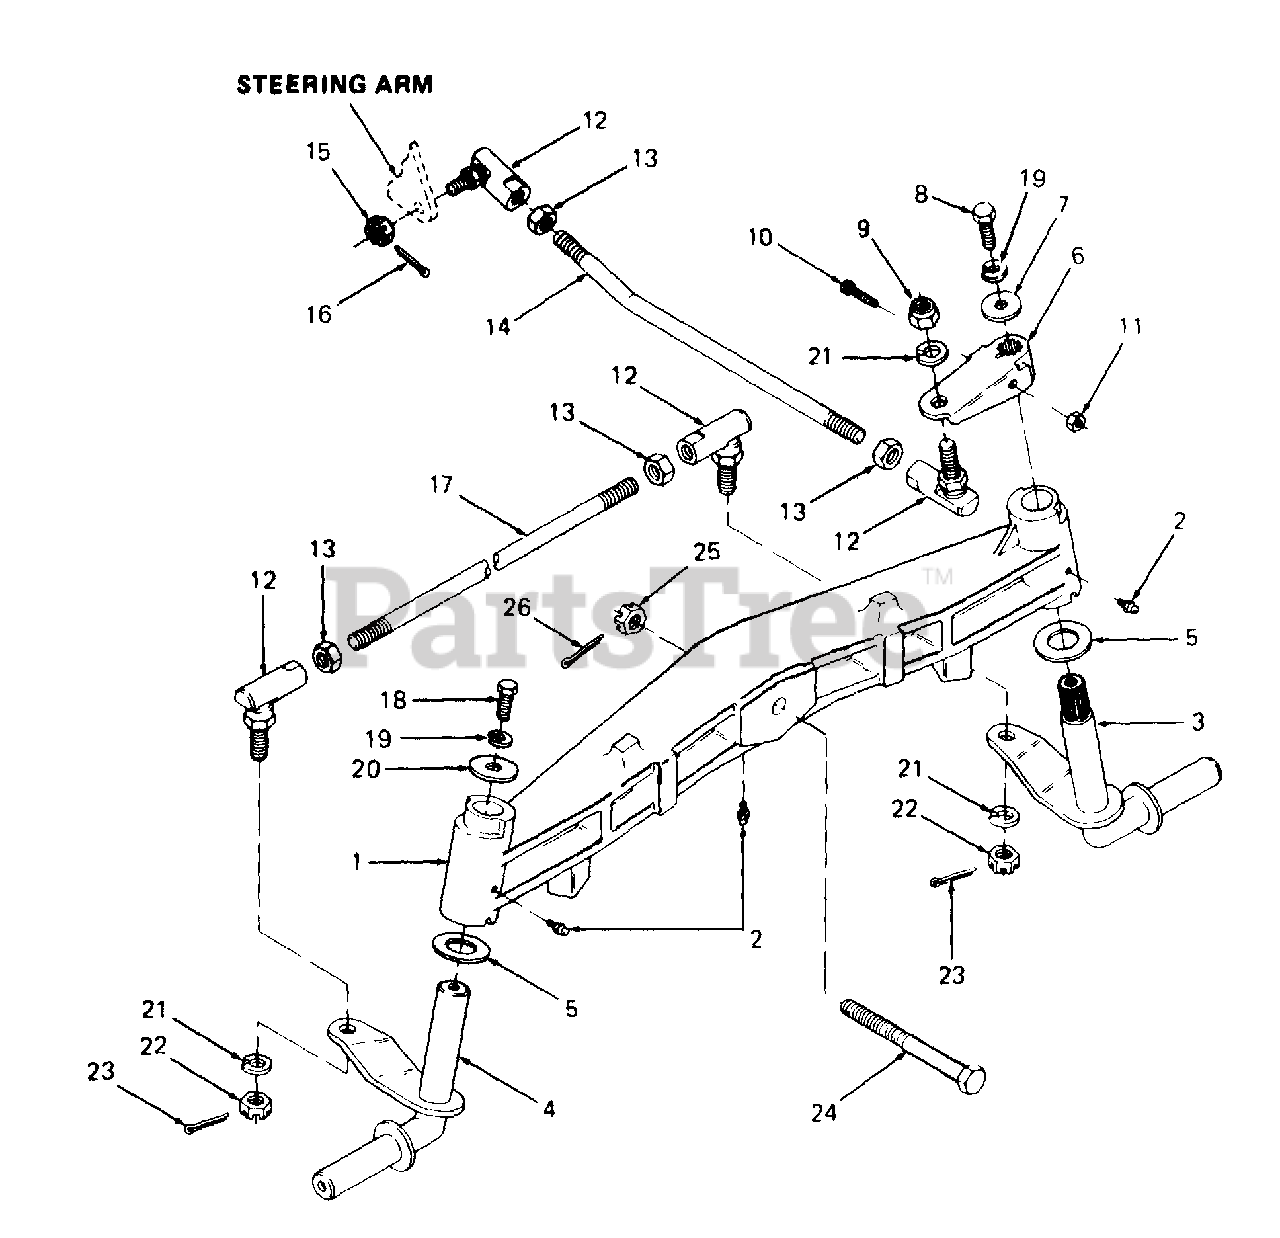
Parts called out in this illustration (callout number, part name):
3	Knuckle, Steering - LH
4	Knuckle, Steering - RH
5	Washer, Thrust, 1.03 X 1.62 X .03 Thk HDN
6	Arm, Steering
7	Washer, Flat, .406 X 1.25 X .157 Thk
8	Screw, Hex Cap, 3/8-24 X 1.0 Lg
9	Nut, Hex Top Lock, 1/2-20
10	Screw, Socket Hd Cap, 1/4-20 X 1.38 Lg
11	Nut, Hex Patch Lock, 1/4-20
12	Ball Joint
13	Nut, Hex Jam, 1/2-20 GR5
14	Link, Drag
15	Nut, Hex Castle, 1/2-20 GR5
16	Pin, Cotter, 3/32 Dia X 1.25 Lg
18	Screw, Hex Cap, 3/8-24 X 1.0 Lg
19	Washer, Lock, 3/8
20	Washer, Flat, .406 X 1.5 X .12 Thk
21	Washer, Lock, 1/2
22	Nut, Hex Castle, 1/2-20 GR5
23	Pin, Cotter, 3/32 Dia X 1.25 Lg
24	Bolt, Hex, 3/4-10 X 5.25 Lg GR5
25	Nut, Hex Castle, 3/4-10
26	Pin, Cotter, 1/8 Dia X 1.5 Lg
